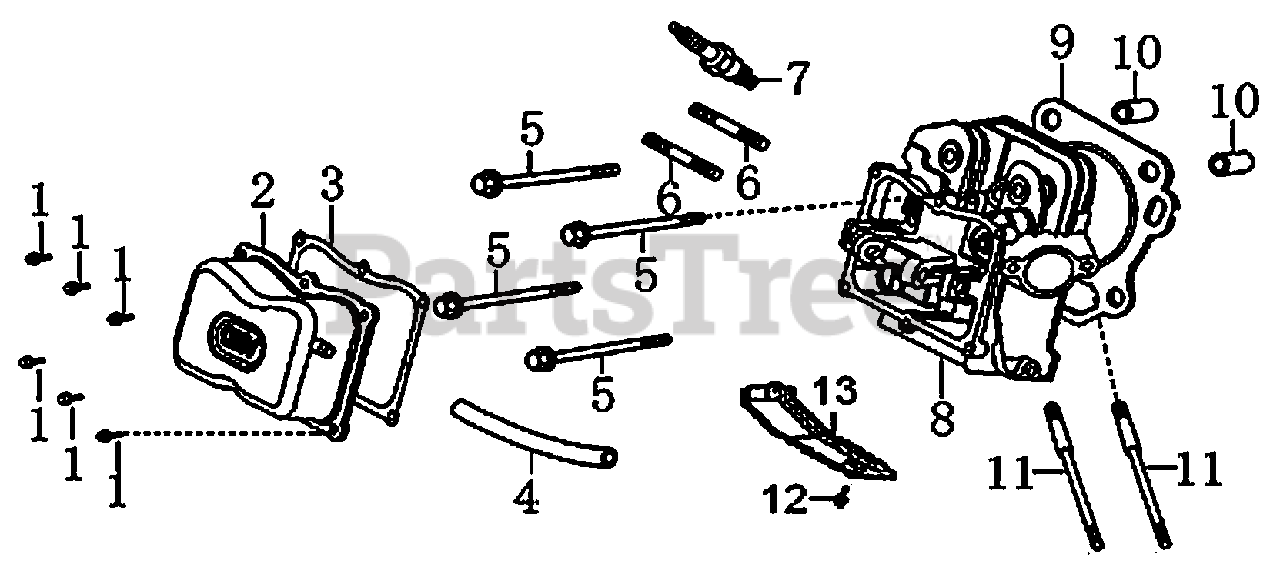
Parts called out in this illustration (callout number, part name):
1	BOLT, FLANGE
2	COVER COMP. HEAD
3	GASKET, HEAD COVER
4	TUBE, BREATHER
5	BOLT, FLANGE, 10×80
6	BOLT, STUD, EXHAUST
7	SPARK PLUG
8	CYLINDER HEAD
9	GASKET, CYLINDER HEAD
10	PIN, DOWEL
11	BOLT, STUD, INTAKE
12	BOLT, FLANGE M6×12
